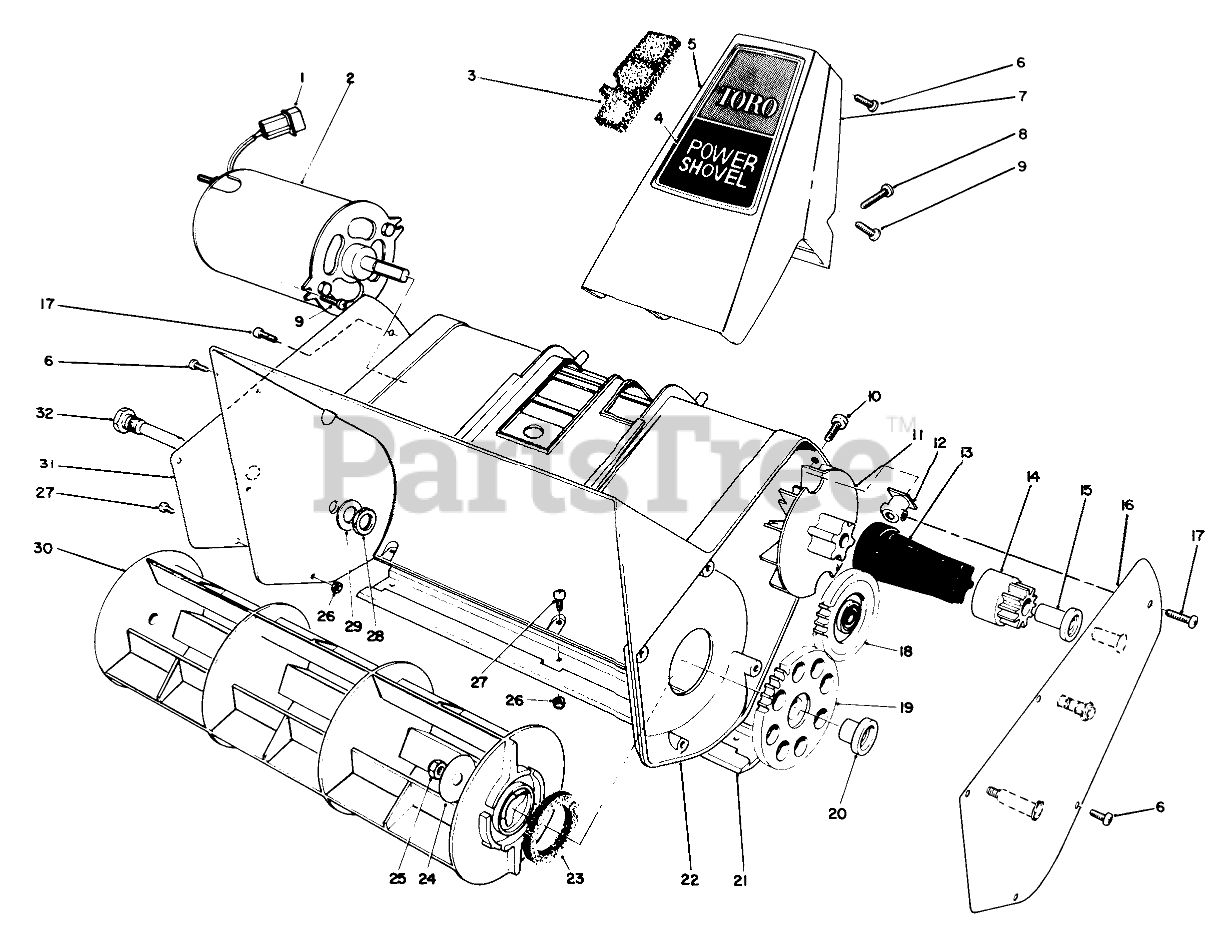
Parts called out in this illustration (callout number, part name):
1	HSG PIN CONNECTOR
2	MOTOR, POWER SHOVEL
3	FOAM FILTER
4	HANDLE SUPT DECAL
5	HANDLE SUPPORT, FRONT
6	SCREW-PPH
7	Handle Support-Back
8	SCREW-PPH
9	SCREW-PPH
10	#10-10X3/4 PLASCREW
11	FAN, POWER SHOVEL
12	MOUNTING BLOCK
13	DRIVE COUPLING
14	Drive Gear (Incl. Ref. #15)
15	BUSHING, DRIVE GEAR
16	Gear Carrier
17	Screw
18	IDLER GEAR ASM
19	Rotor Gear Assembly (Incl. Ref. #20)
20	BUSHING, ROTOR GEAR
21	Scraper
22	Housing
23	FELT WASHER
24	ROTOR WASHER
25	NUT-LOCK, NI
26	NUT-LOCK
27	SCREW-PPH
28	NUT-LOCK, CONE
29	WASHER-FLAT
30	ROTOR
31	RT. SIDE COVER (RAW)
32	ROTOR PIN
